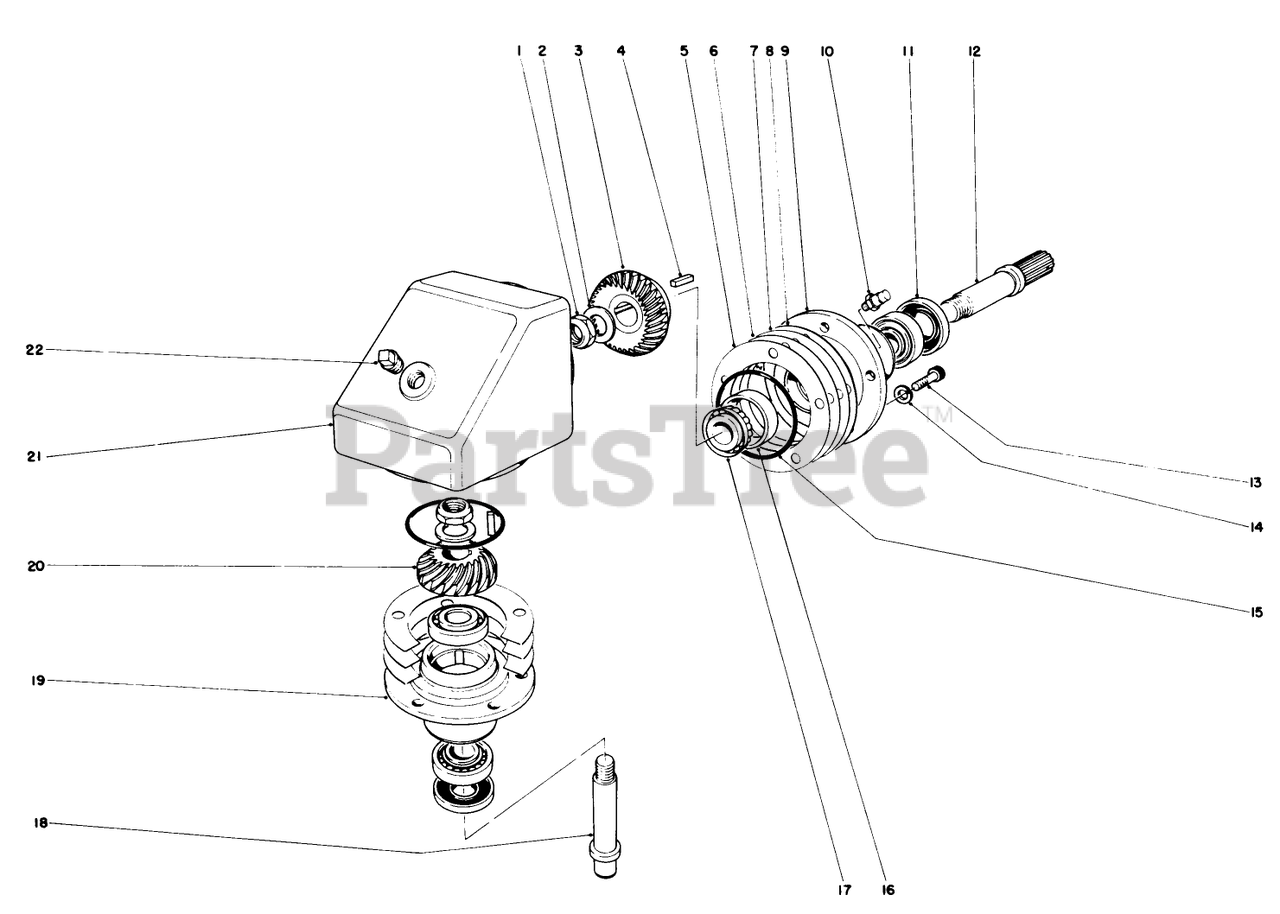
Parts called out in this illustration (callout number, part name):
1	NUT-LOCK, NI
2	THRUST WASHER
4	KEY-SQUARE
5	.002 SHIM (RED)
6	.005 SHIM (BLUE)
7	.015 SHIM (PINK)
9	INPUT BRG HSG
11	OIL SEAL
12	INPUT SHAFT
13	SCREW-HSH
14	WASHER-LOCK
15	O-RING
16	BEARING-CUP
17	CONE-BEARING
18	OUTPUT SHAFT
19	OUTPUT BRG HSG
20	PINION
21	GEAR BOX
22	3/8-18 SQ HD PLUG/MAG
